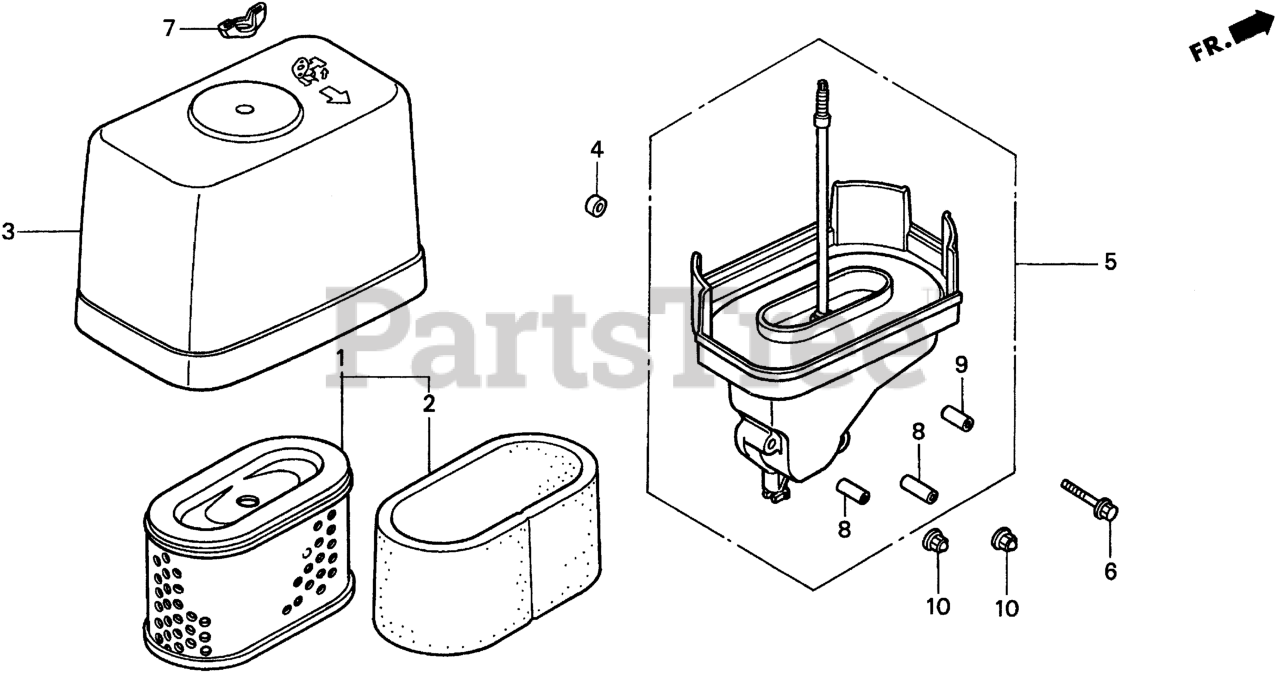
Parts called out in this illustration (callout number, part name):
1	ELEMENT, AIR CLEANER (PLASTIC BASE)
2	FILTER (OUTER)
3	COVER, AIR CLEANER
4	SPACER, AIR CLEANER ELBOW
5	ELBOW COMP., AIR CLEANER
6	BOLT, FLANGE (6X45)
7	WINGNUT, TOOL BOX SETTING
8	COLLAR, AIR CLEANER
9	COLLAR, AIR CLEANER
10	NUT, FLANGE (6MM)
